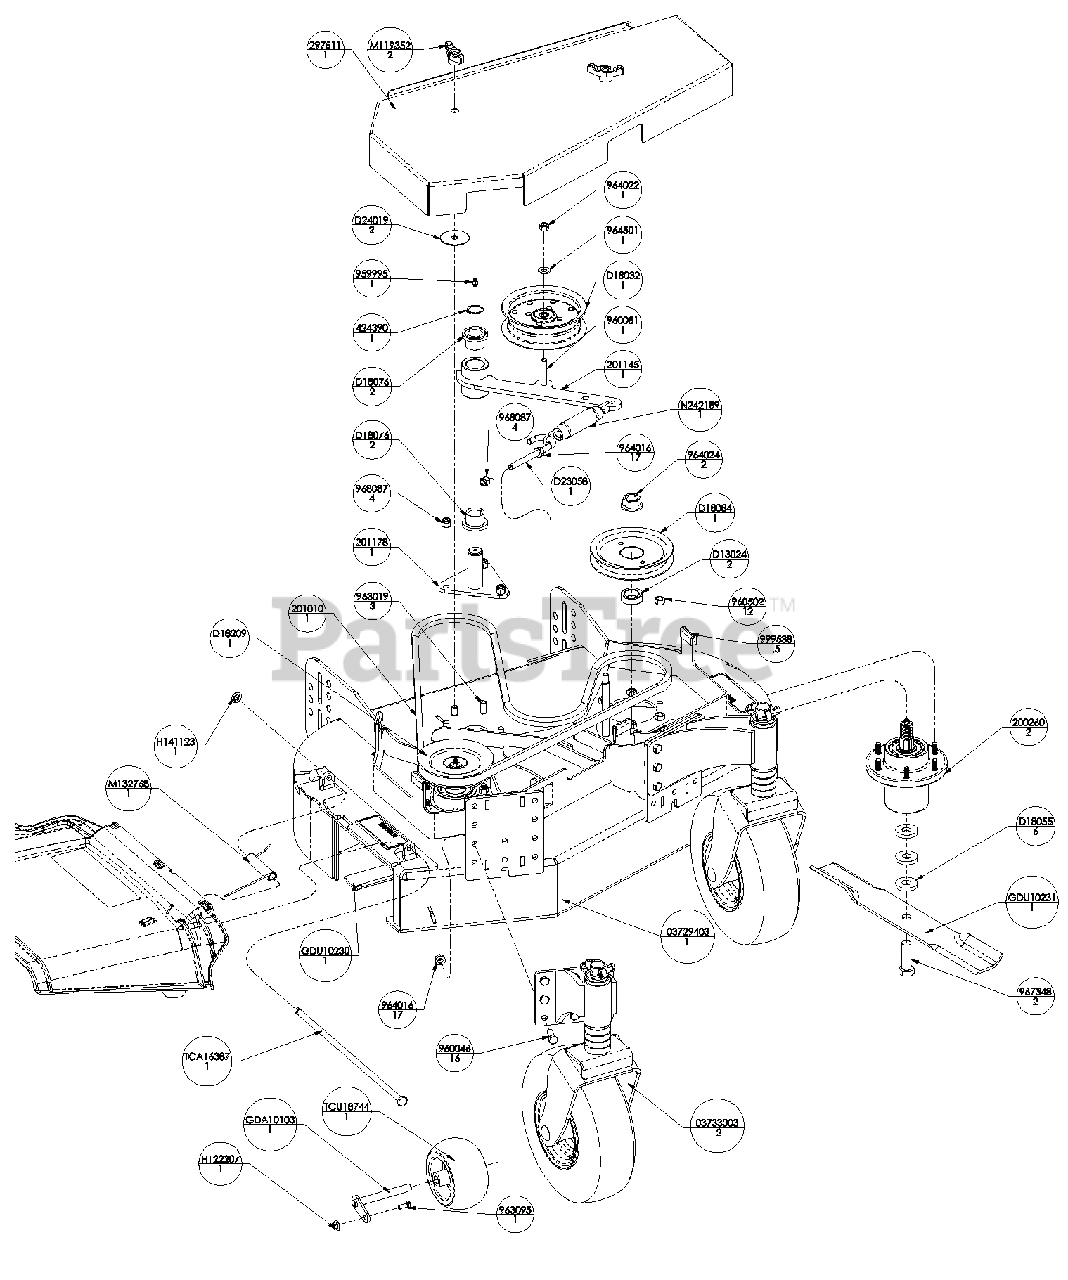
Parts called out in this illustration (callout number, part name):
1	SPACER, SPINDLE TOP-PULLEY
2	PULLEY, FLAT 5.00X.375 W/BRG
3	WASHER, .630X1.50X.250 FLAT Y
4	BRG, FLG 1.00X1.25X1.00
5	SPLINE, SPINDLE PULLEY OFFSET
6	PULLEY, SMALL W/TALL HUB
7	WASHER, .402X2.00X.055 FEND Y
8	J-BOLT, 3/8-16 X 4.00 Y
9	PIVOT, RETAINER WELD
10	BLADE, 16.500 X .80 LIFT
11	BLADE, 18.000 X .80 LIFT
12	NUT-1/4" FLANGE PREVAILING TOR
13	RETAINER #
14	SPRING,CHUTE GUARD
15	KNOB, 3/8-16 INSERT
16	SPRING, EXT
17	CHUTE DISCHARGE ASSY #
18	WHEEL, GAGE
19	ASSY, SPINDLE HOUSING
20	BELT, HB 80.3 EL AMD OHR
21	WLDT, IDLER ARM
22	WLDT, FIXD DECK EVRDE W/DECALS
23	ASSY, FR WHEEL CASTER
24	SHIELD, DECK 34 W/DECALS EVRDE
25	WLDT, IDLER PIVOT
26	SNAP RING, 1.00 X .042 EXT
27	FTG, 1/4-28 STRGT GREASE ZERK
28	BOLT, 3/8-16X1.00 HEX 5 Y
29	BOLT, 3/8-16X2.25 HEX 5 Y
30	NUT, 3/8-16 STD HEX GR5 Y
31	BOLT, 3/8-16X1.00 CRG 5 SN Y
32	BOLT, 1/4-20X.750 CRG 5 Y
33	LOCKNUT, 3/8-16 WHIZ Y
34	LOCKNUT, 3/8-16 CROWN Y
35	WASHER, .406X.813X.065 FLAT Y
36	LOCKNUT, 3/4-16 CROWN PL
37	BOLT, 5/8-11 X 2.00 HEX 8 Y
38	LOCKNUT, 3/8-16 NYLOC Y
39	TRIM, LOCK 1/4" EDGE
